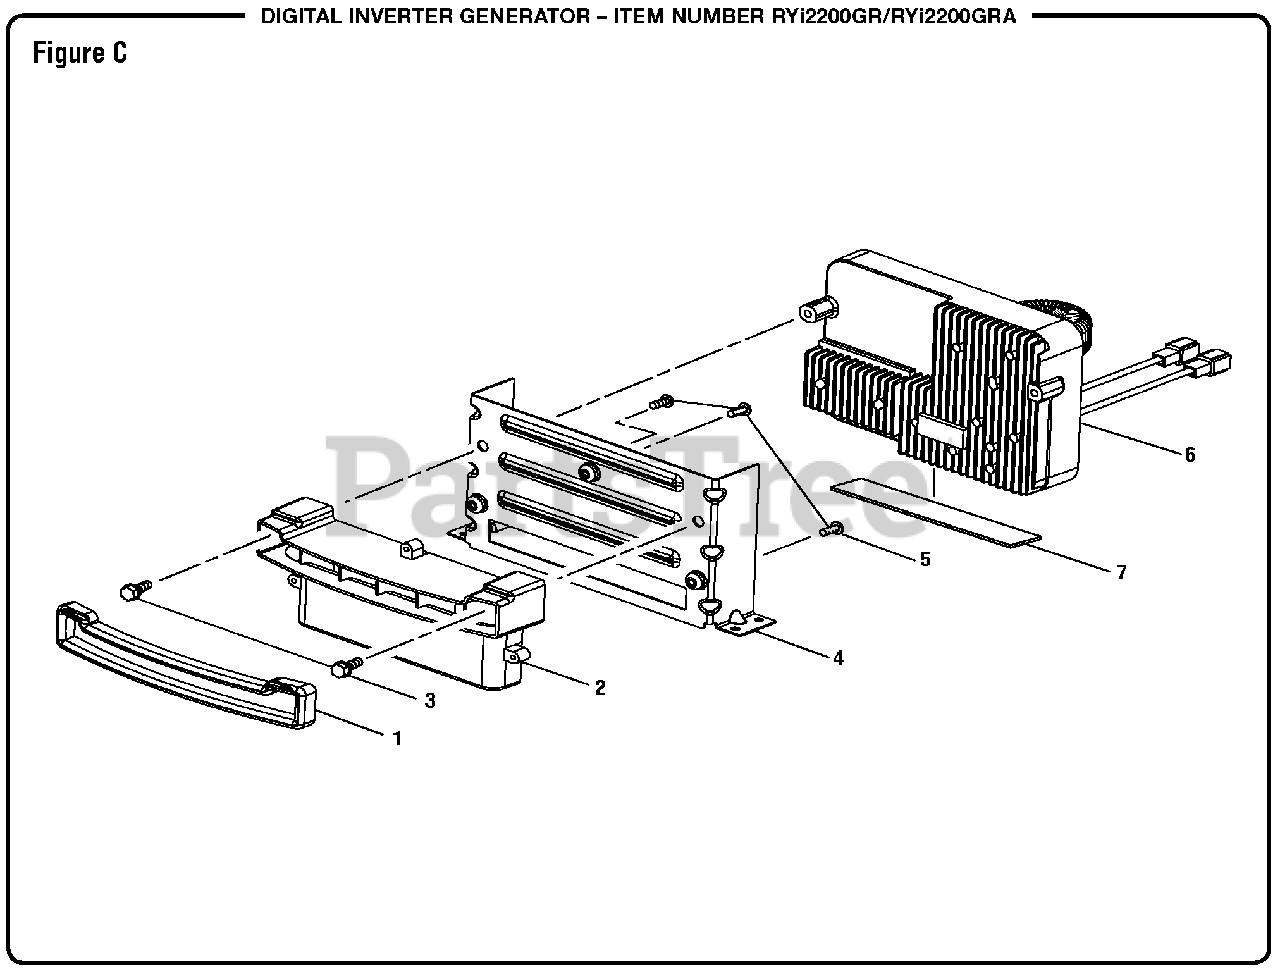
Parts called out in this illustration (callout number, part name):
1	Edge Trim Rubber
2	Engine Intake Baffle
3	Bolt (M6 x 12mm, Hex Hd.)
4	Inverter Module Bracket
5	Screw (M4 x 10 mm, T20 Torx Hd.)
6	Inverter Module
7	Rubber Pad
